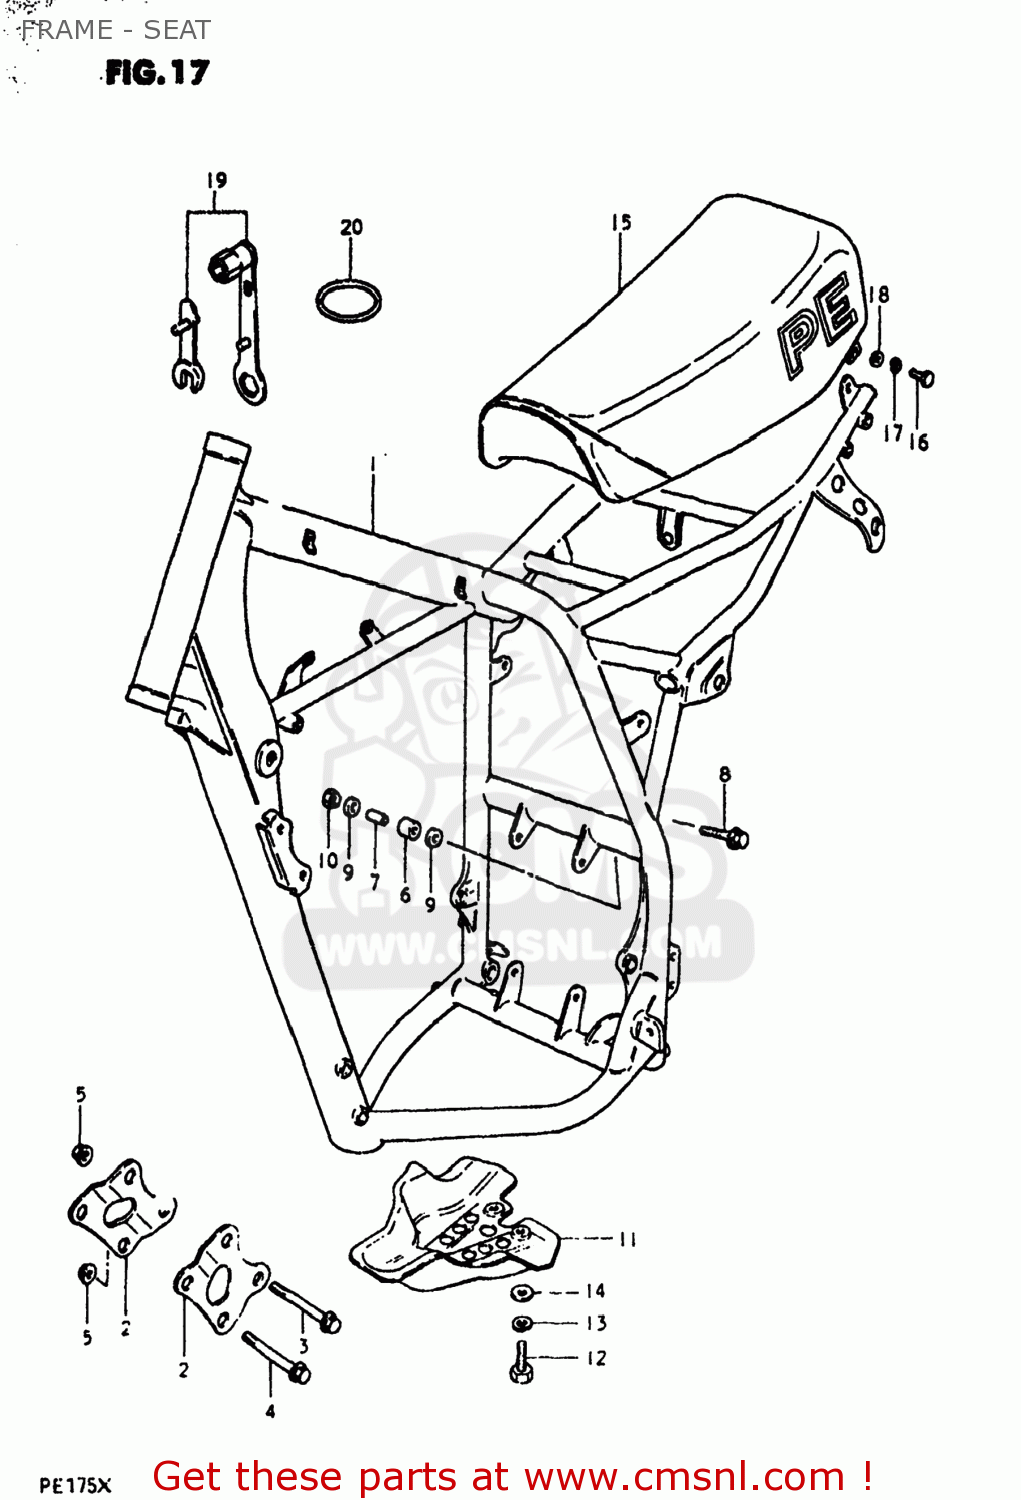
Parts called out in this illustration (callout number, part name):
1	FRAME
2	PLATE,ENGINE MOUNTING
3	BOLT(8X67)
4	BOLT
5	NUT
6	ROLLER,CHAIN CONTROL
7	SPACER,CHAIN LENGTH ROLLER
8	BOLT(8X45)
9	WASHER
10	NUT
11	PROTECTOR,ENGINE
12	BOLT
13	LOCK WASHER
14	WASHER (8.2X20X1.6)
15	SEAT ASSEMBLY
16	BOLT
17	LOCK WASHER
18	WASHER (8.2X20X1.6)
19	SPARK PLUG WRENCH
20	O RING TOOL FITTING
